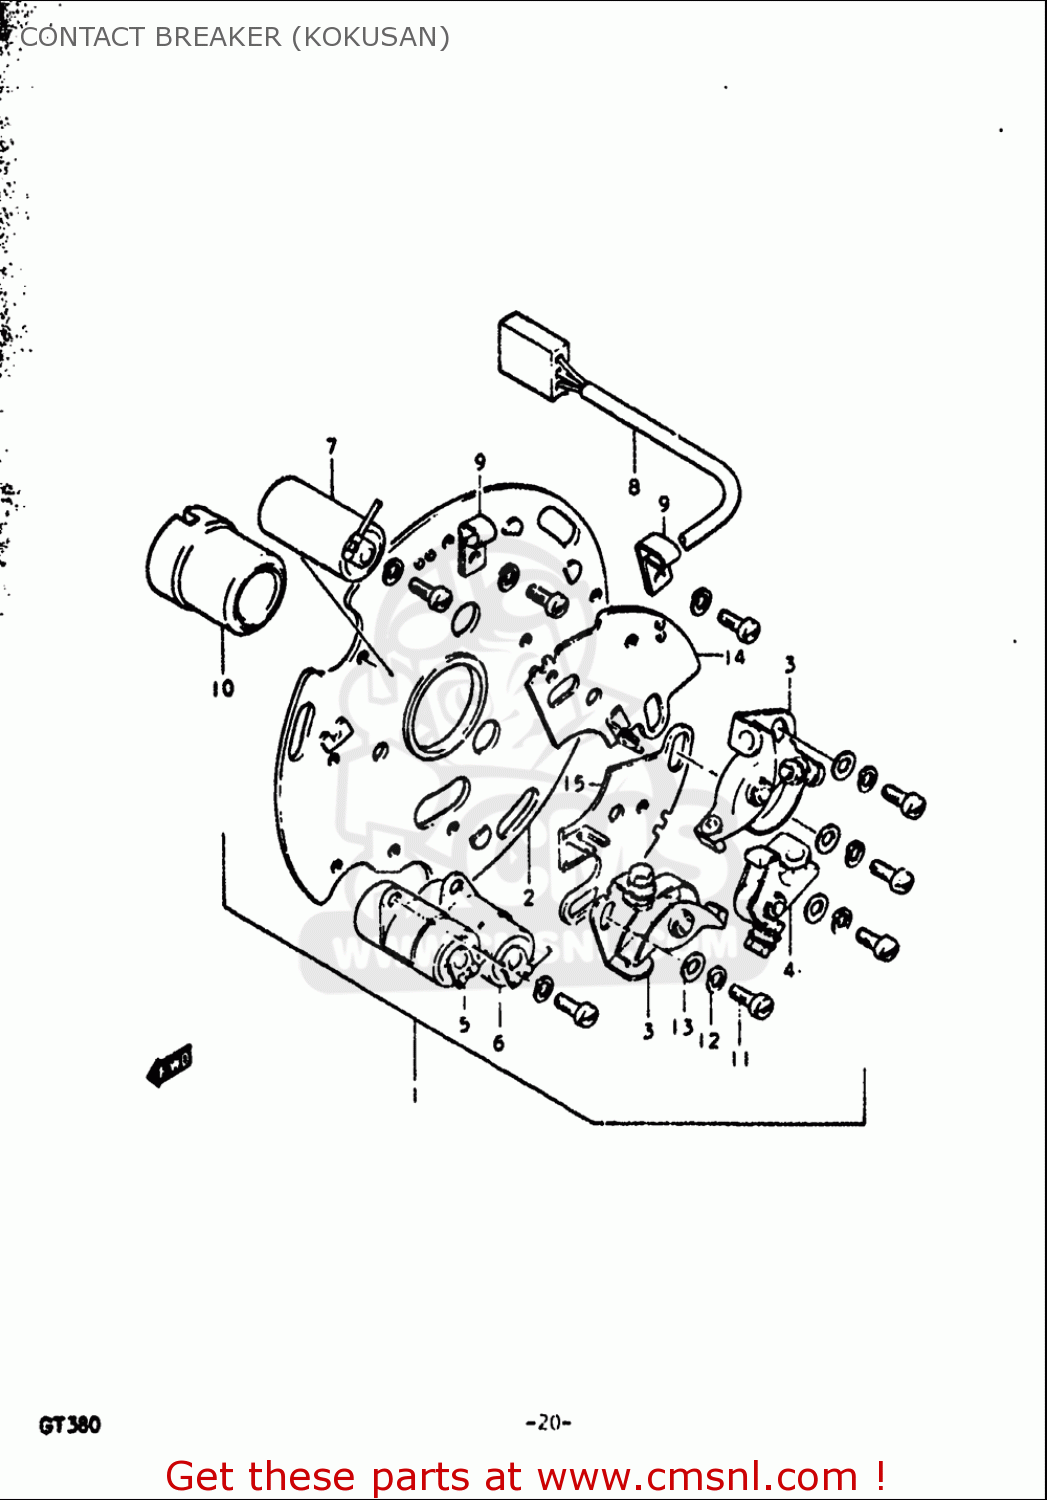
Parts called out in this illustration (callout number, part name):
3	POINT ASSY,CONTACT
4	POINT,CTR
7	CONDENSER,R
11	SCREW 4X6
12	WASHER,LOCK
13	WASHER
